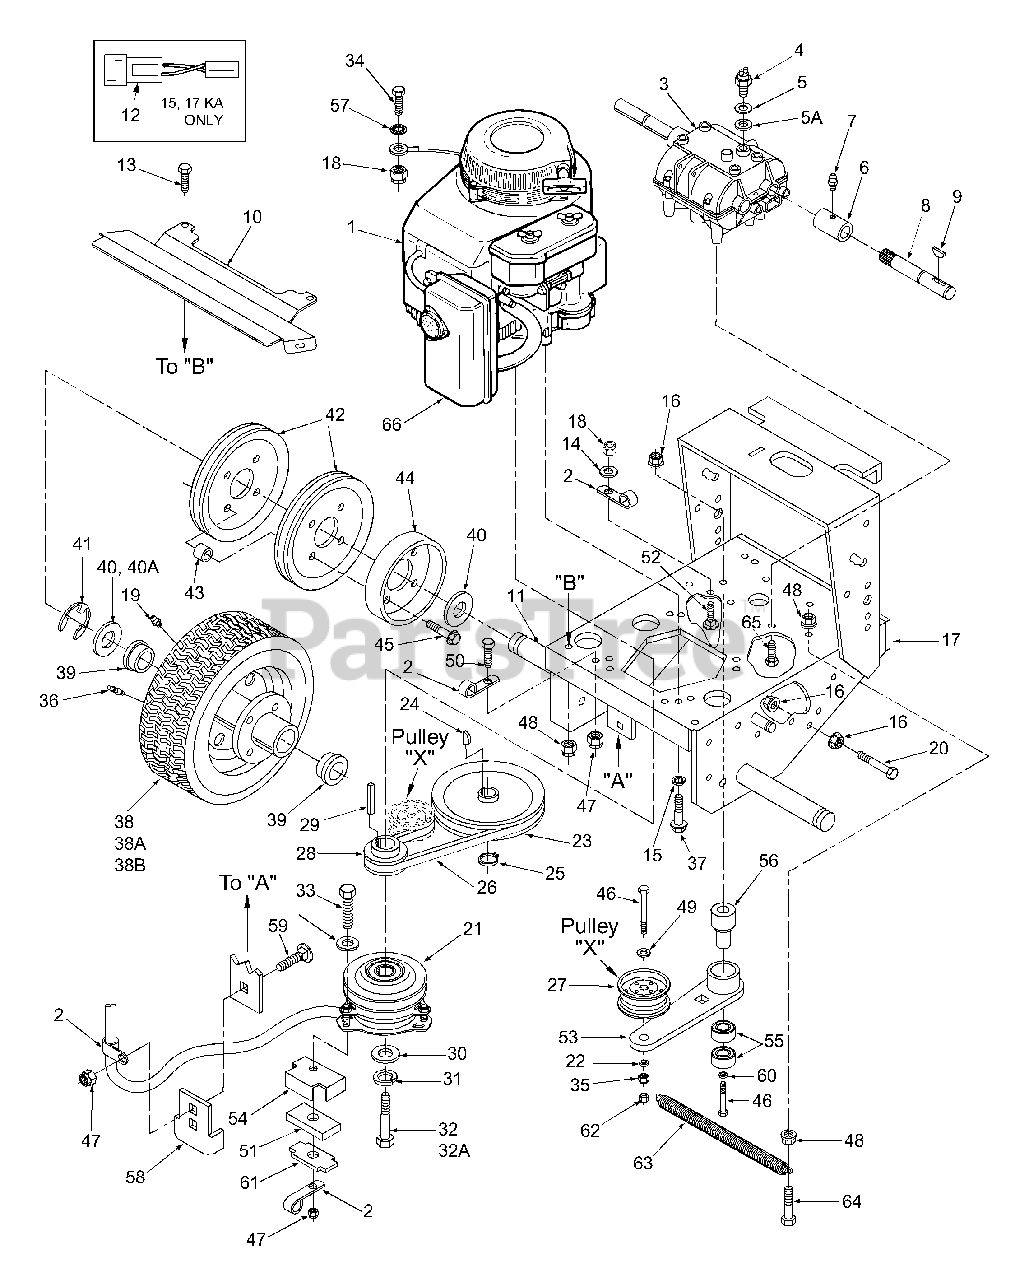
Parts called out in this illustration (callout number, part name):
1	Engine,15HP Kawasaki (FH451V - AS02)
1	Engine, 17HP Kawasaki (FH500V)
2	Cable Clamp
3	Transmission, 5-speed (Peerless 700-070, 9 spline)
4	Neutral Safety Switch
5	Fibre Washer, thin
5A	Fibre Washer, thick
6	Coupler, Jackshaft
7	Grease Fitting, straight 1/4-28
8	Jackshaft
9	Key, Hi-Pro #9
10	Heat Shield, 36" & 48"
10	Heat Shield, 52"
11	Wheel Axle (SW36,48)
12	Wire Harness Adaptor, 17KA
13	Bolt, 5/16-18 X .75" Serrated Flange Hex Head
14	Flat Washer 1/4" (.312 X .75 X .065)
15	Lock Wshr. 5/16"
16	Nut, 3/8-16 Serrated Flange
17	Engine Deck
18	Nut, 1/4-20 Elastic Stop
19	Grease Fitting, 1/4-28 Self Tap
20	Bolt, 3/8-16 x 3-3/4" Hex Head
21	Electric Clutch (Ogura)
22	Washer, 3/8" (.391 x .938 x .105)
23	Pulley, Transmission Input
24	Key, Woodruff #9
25	Retaining Ring, 5/8" Ext, Basic
26	Belt, Transmission Drive
27	Idler Pulley, Transmission
28	Pulley, Traction Drive
29	Key, 1/4 x 1/4 x 3/4"
30	Flat Washer, 7/16" Special
31	Lock Washer,7/16"
32	Bolt, 7/16-20 x 2-1/2" Hex Head (Kohler Only)
32A	Cpsrw, M10-1.5 x 55 Metric Hex Hd (Kawasaki)
33	Bolt, 5/16-18 x 1-3/4" Hex Head
34	Bolt, M8-1.25 x 1.0
35	Nut, 3/8-16 Elastic Stop
36	Valve Stem
37	Bolt, M8-1.25 x M25 Metric Hex Hd
38	Wheel Assembly
38A	Tire, 15 x 6.0-6, Turf Saver
38B	Rim & Bearing Assembly
39	Wheel Brng. NWC (OD 1.984 - 1.980)
40	Washer, 1-1/16 x 1-3/4 x 12 ga
40A	Washer, 1-1/16 x 1-1/2 x 18 ga
41	Retaining Ring, 1" Ext.- "E"
42	Pulley, Wheel Drive
43	Spacer, Wheel Pulley
44	Brake Drum
45	Bolt, 5/16-18 x 1-1/2" Serrated Flange
46	Capscrew, Hex Head 3/8-16 x 2.75"
47	Nut, 5/16-18 Elastic Stop
48	Nut, 5/16-18 Serrated Flange Hex Head
49	Flatwasher, 3/8 (.391 x .938 x .105)
50	Bolt, 5/16-18 x .75" Hex Head
51	Rubber Pad, Clutch Stop
52	Bolt, 1/4-20 x .75" Carriage
53	Idler Arm, Trans. Drive
54	Backing Plate
55	Ball Bearing
56	Hub Idler Pivot
57	Lock Washer Internal Tooth
58	Anti Rotation Bracket
59	Bolt, 5/16-18 x 1" Carriage
60	Flatwasher, 3/8 (.391 x .938 x .105 HD) Grade 8
61	Plate, Backing
62	Nut, 3/8-16 Elastic Stop
63	Spring, Return Drive Idler
64	Bolt, Hex Head 3/8-16 x 2.75"
65	Capscrew, 5/16-18 x .75 Serrated Flange Hex Head
66	Muffler, Kohler
66	17KA Muffler
